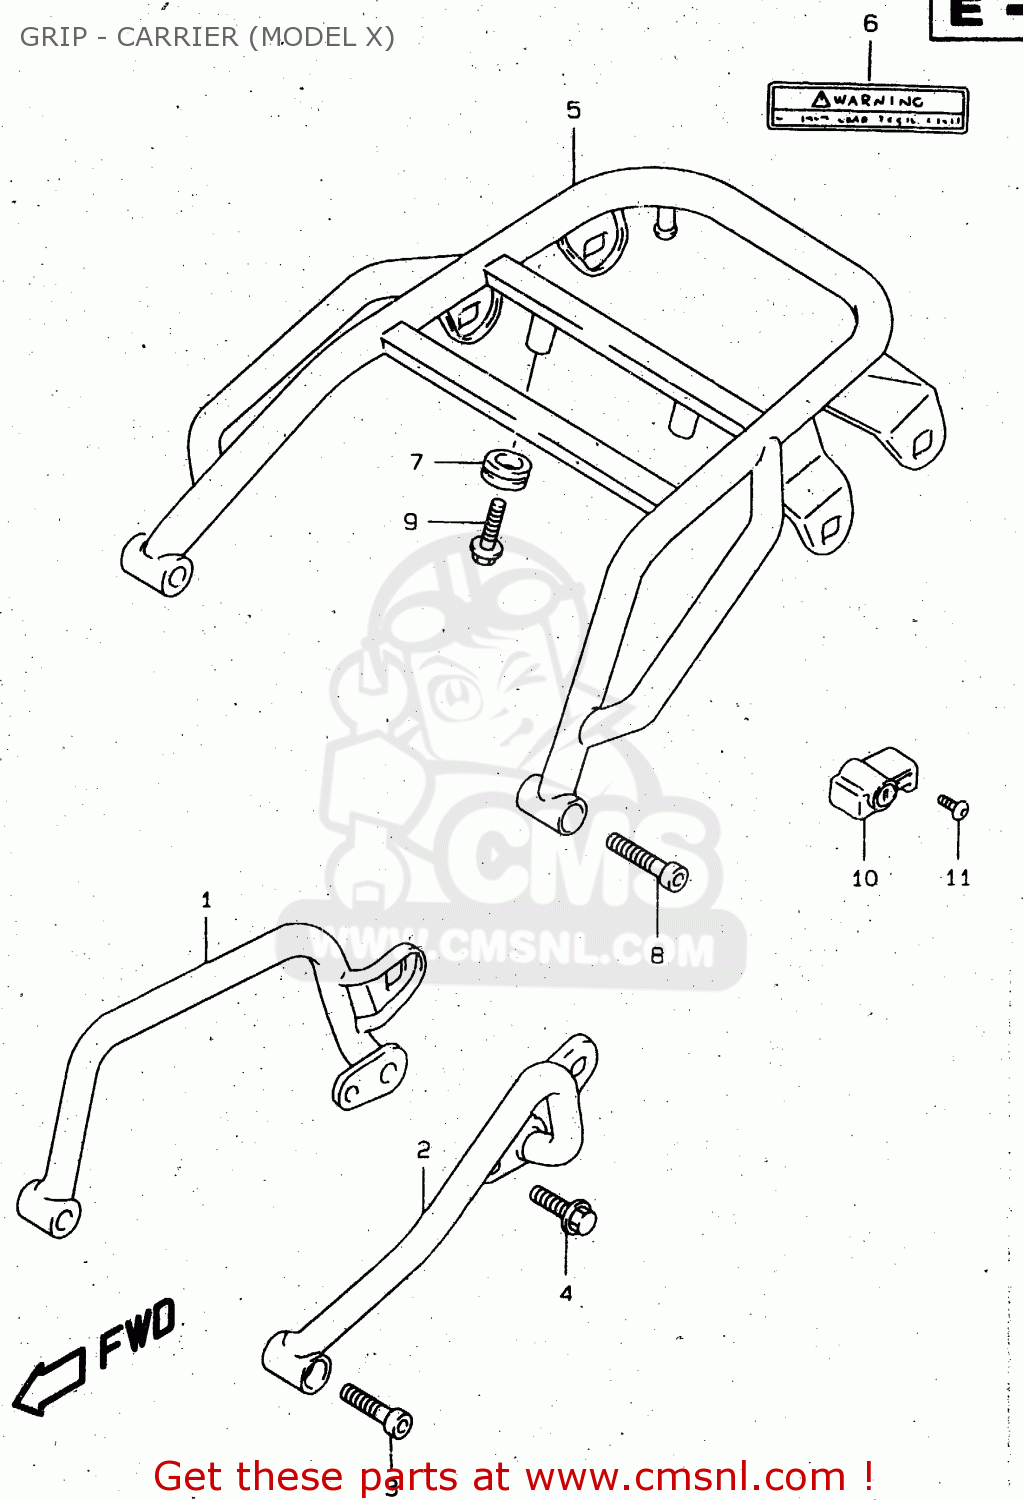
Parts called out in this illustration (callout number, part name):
1	GRIP,RR,R
2	GRIP,RR,L
3	BOLT
4	BOLT
5	DR650 REAR RACK
6	LABEL,WARNING RR CARRIER
7	GROMMET
8	BOLT
9	BOLT
10	LOCK SET,HELMET
11	SCREW(6X14)
